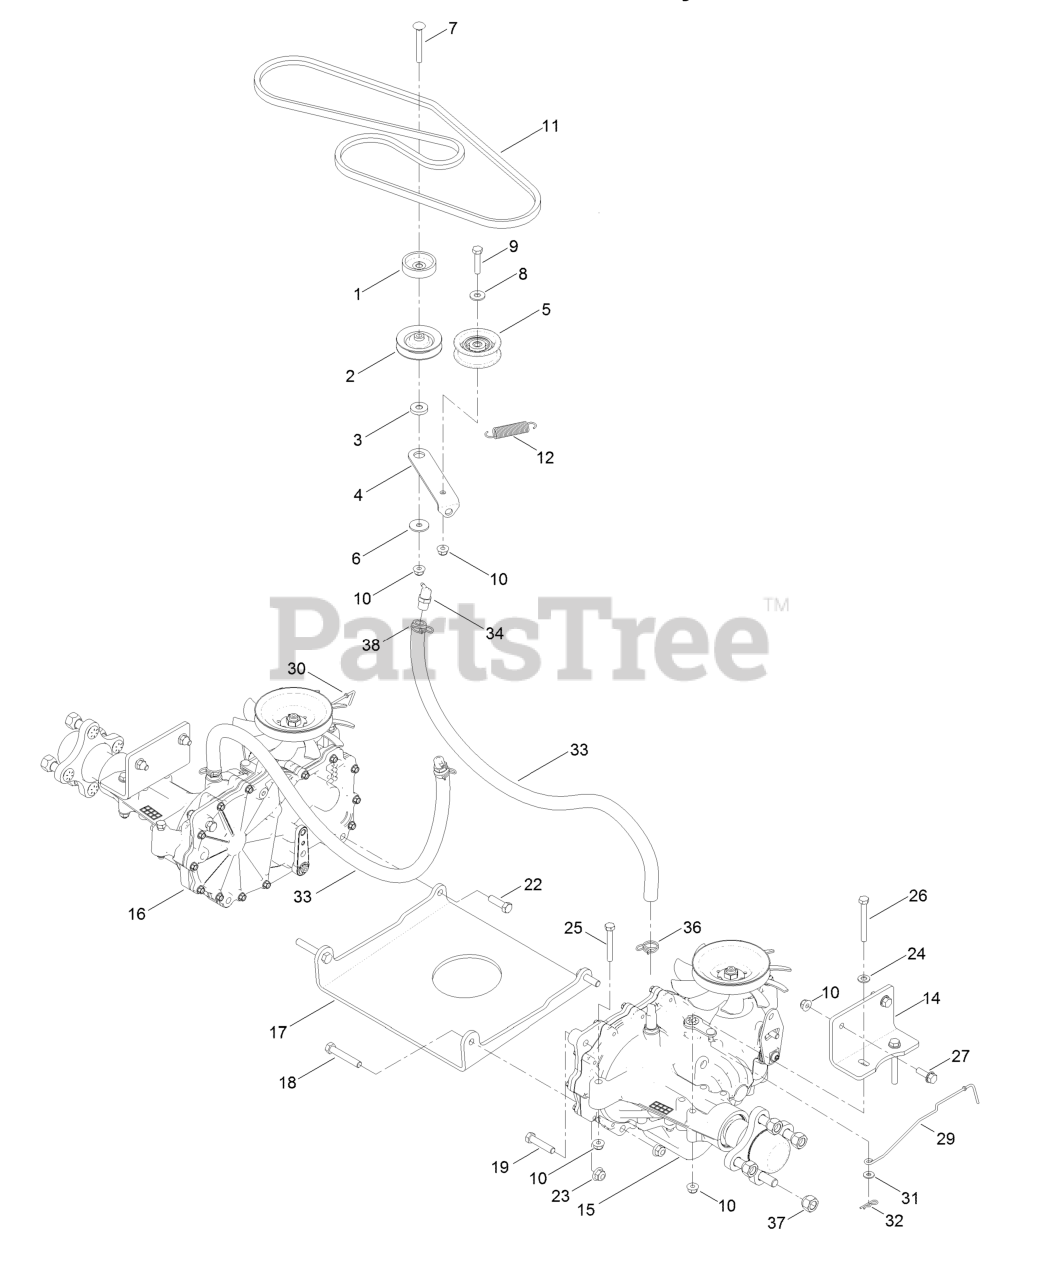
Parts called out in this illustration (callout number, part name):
2	PULLEY-IDLER
3	SPACER-ARM, IDLER
4	ARM-IDLER
5	PULLEY-IDLER
6	WASHER-PIVOT
7	SCREW-CARR
8	WASHER-FLAT
9	SCREW-HH
10	NUT-HF, NI
11	V-BELT
12	SPRING-RETURN, PEDAL
14	MOUNT-HYDRO
15	LH HYDRO TRANSMISSION ASM
16	RH HYDRO TRANSMISSION ASM
17	PLATE-CROSS, HYDRO
18	SCREW-HH
19	SCREW-HH
22	SCREW-HH
23	NUT-HF, NI
24	WASHER-PLAIN
25	SCREW-HH
26	SCREW-HH
27	SCREW-HHF
29	ROD-BYPASS, LH
30	ROD-BYPASS, RH
33	HOSE-HYDRO
34	BREATHER KIT
36	CLAMP-HOSE
37	NUT-LUG
38	CLAMP-HOSE
